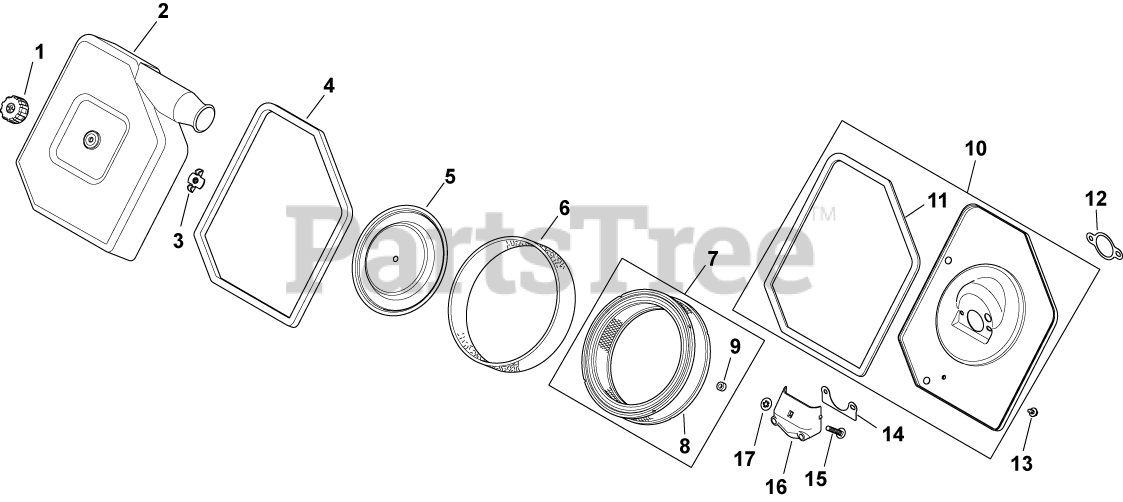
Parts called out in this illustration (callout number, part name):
2	COVER, AIR CLEANER - DISCONTINUED
3	NUT, WING
4	SEAL, AIR CLEANER
5	COVER, AIR CLEANER
6	PRE-CLEANER
7	KIT, AIR CLEANER ELEMENT
8	ELEMENT, AIR CLEANER (KM) - Also available Retail Packaged 47 883 01-S1 Air Filter Kit
9	SEAL, INNER AIR CLEANER
10	BASE, AIR CLEANER - DISCONTINUED
11	SEAL, AIR CLEANER
12	GASKET, AIR CLEANER BASE
13	SCREW, FLG THD FRM M5X.8X10
14	GASKET, AIR CLEANER BASE
16	CUP, FUEL SPITBACK
17	RETAINER, RING
